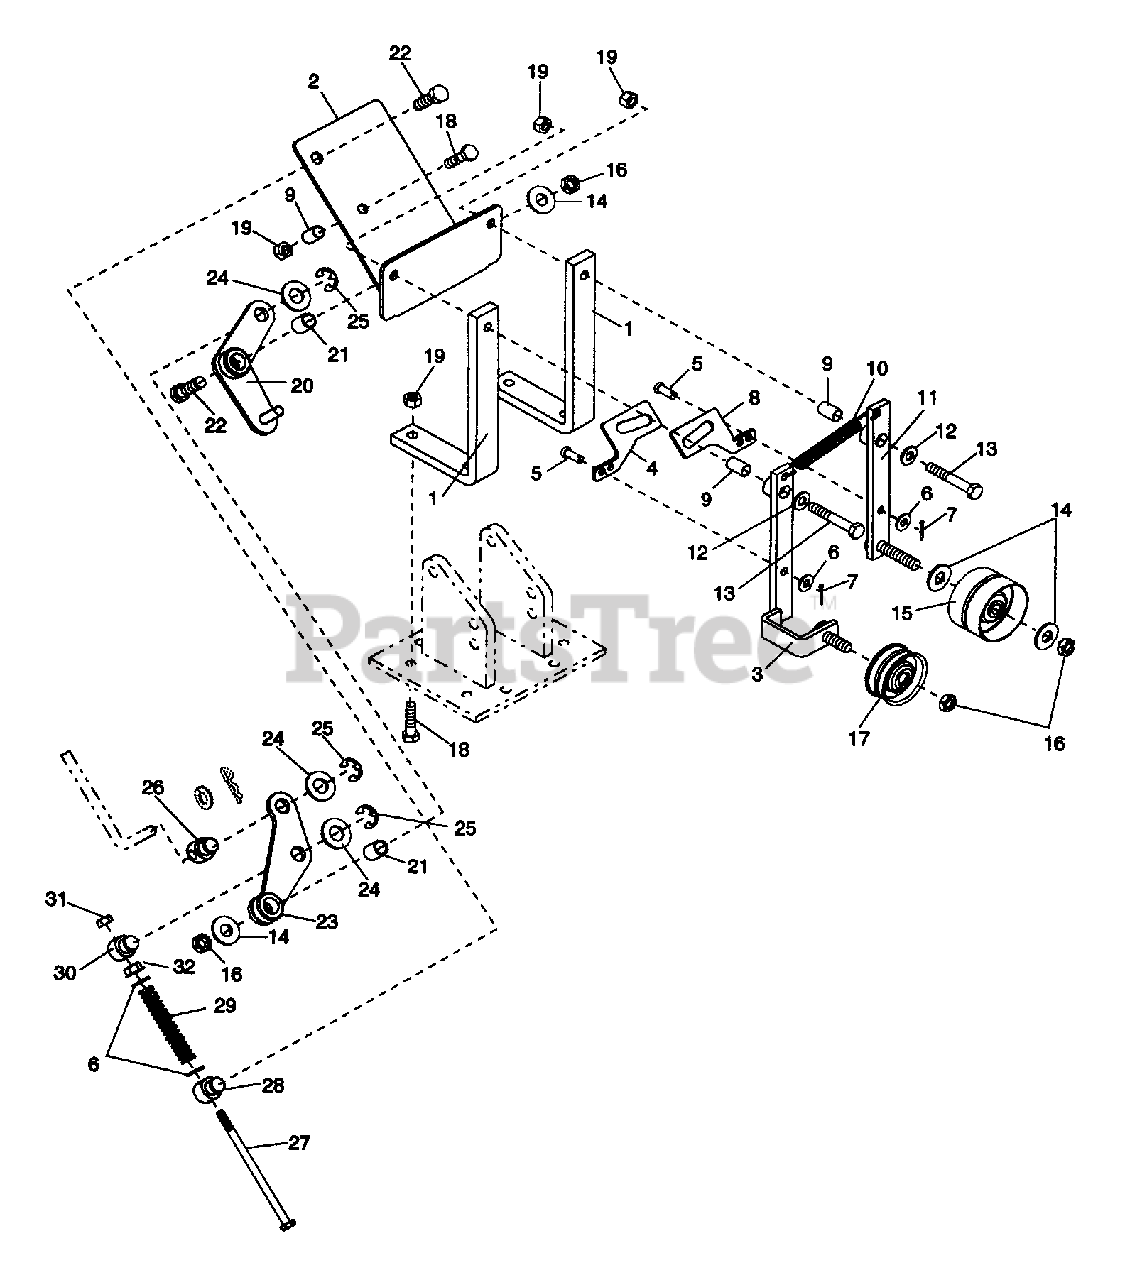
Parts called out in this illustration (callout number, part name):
1	SHIFT MOUNTING BAR
2	SHIFTING PLATE
3	IDLER ARM - REVERSE
4	SHIFT LINK - REVERSE
5	CLEVIS PIN
6	WSHR-FL-STL.281X.62X.065 PL
7	PIN-COTR .06X.50
8	SHIFT LINK - FORWARD
9	SLEEVE BUSHING
10	SG-TENS .067X.437X3.25 WLD 4.5
11	IDLER ARM - FORWARD
12	WSHR-FL-STL.344X.688X.065PL
13	BLT-HEX .31-18X2.00 PL GR2
14	WSHR-FL-STL .438X1.0X.083 PL
15	IDLER-FLAT 2.25 X .38
16	NUT-LK-JAM-CTR .375-16 PL
17	IDLER-FLAT 2.000X.375
18	BLT-HEX .31-18X1.25 PL GR2
19	NUT-LK .312-18 GR A PL
20	BELLCRANK WELDMENT
21	BSHG-SLV .406 X .545 X .68
22	BLT-HEX .38-16X1.25 PL GR 2
23	RODCRANK WELDMENT
24	WSHR-FL-STL .531X1.062X.095 PL
25	RG-RTNG-EXT .500X.042 (E)
26	PIVOT - SHIFT LEVER ROD
27	BLT-HEX .25-20X4.50 PL
28	PIVOT - BELLCRANK
29	SG-COMP .080X.52X2.90
30	THREADED PIVOT - RODCRANK
31	NUT-LK-CTR .250-20 PL
32	NUT-FLG. .312-18 PL
